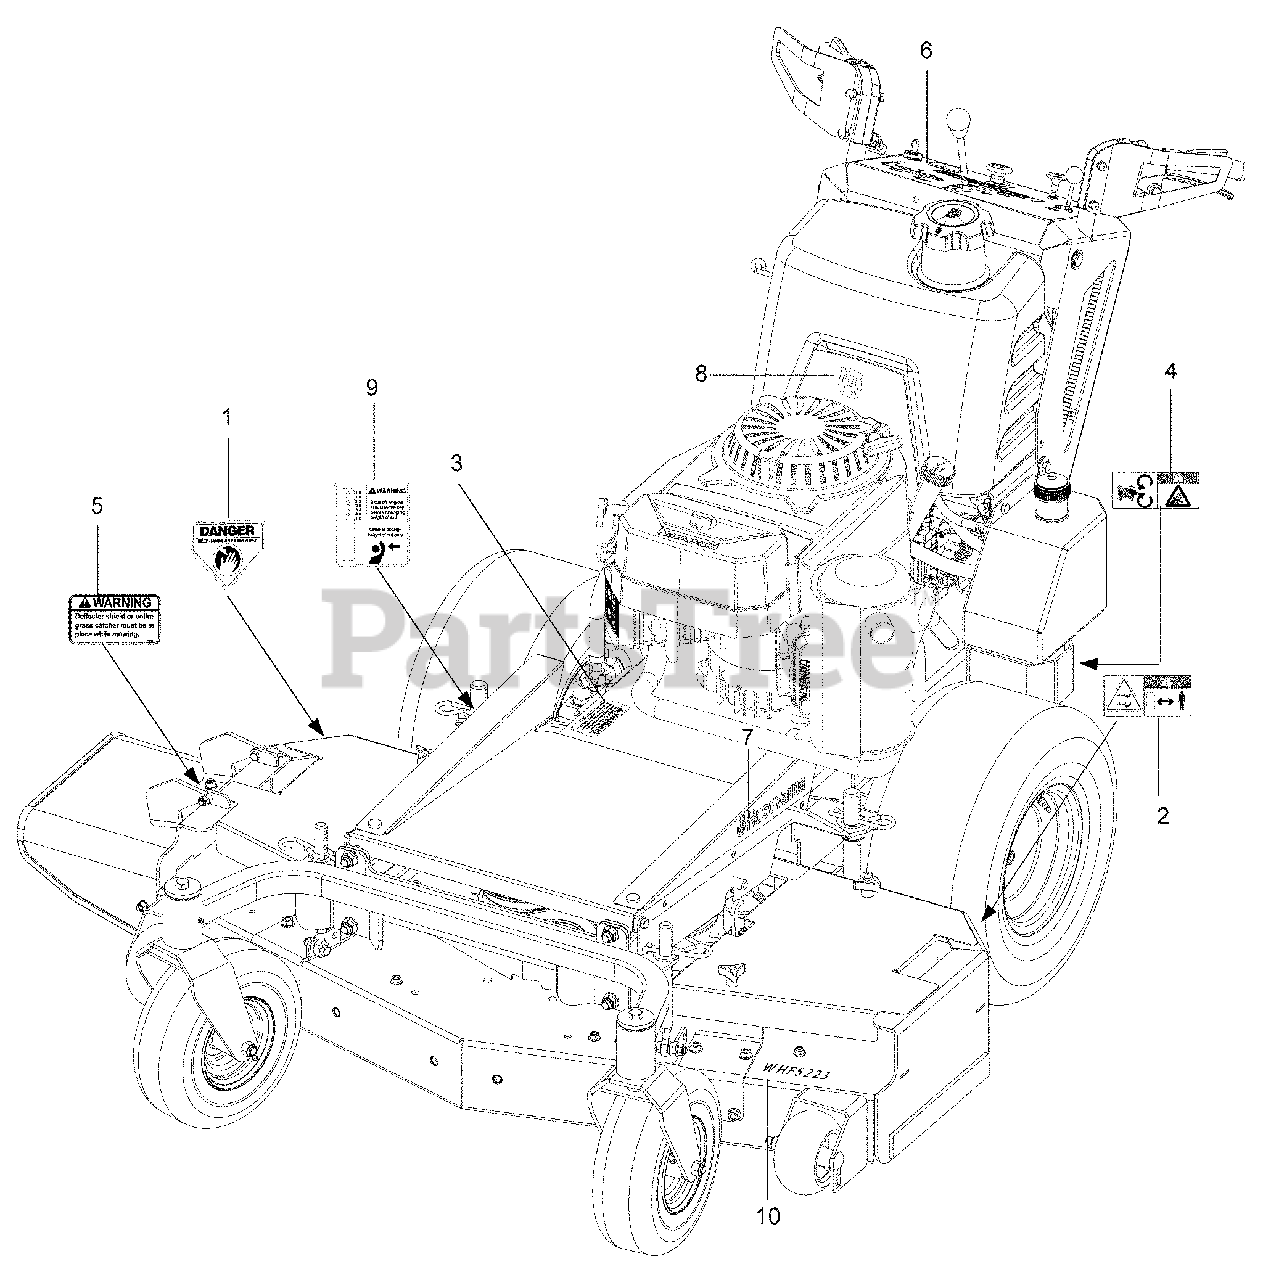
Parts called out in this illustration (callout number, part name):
1	DECAL, WARNING
2	DECAL, SEVERING
3	DECAL, PROP 65
4	DECAL, BELT DRIVES
5	DECAL, WARNING
6	DECAL, INSTRUMENT PNL
7	DECAL, HUSQVARNA
8	DECAL, CROWN
9	DECAL, HEIGHT OF CUT
10	DECAL, WHF5223
